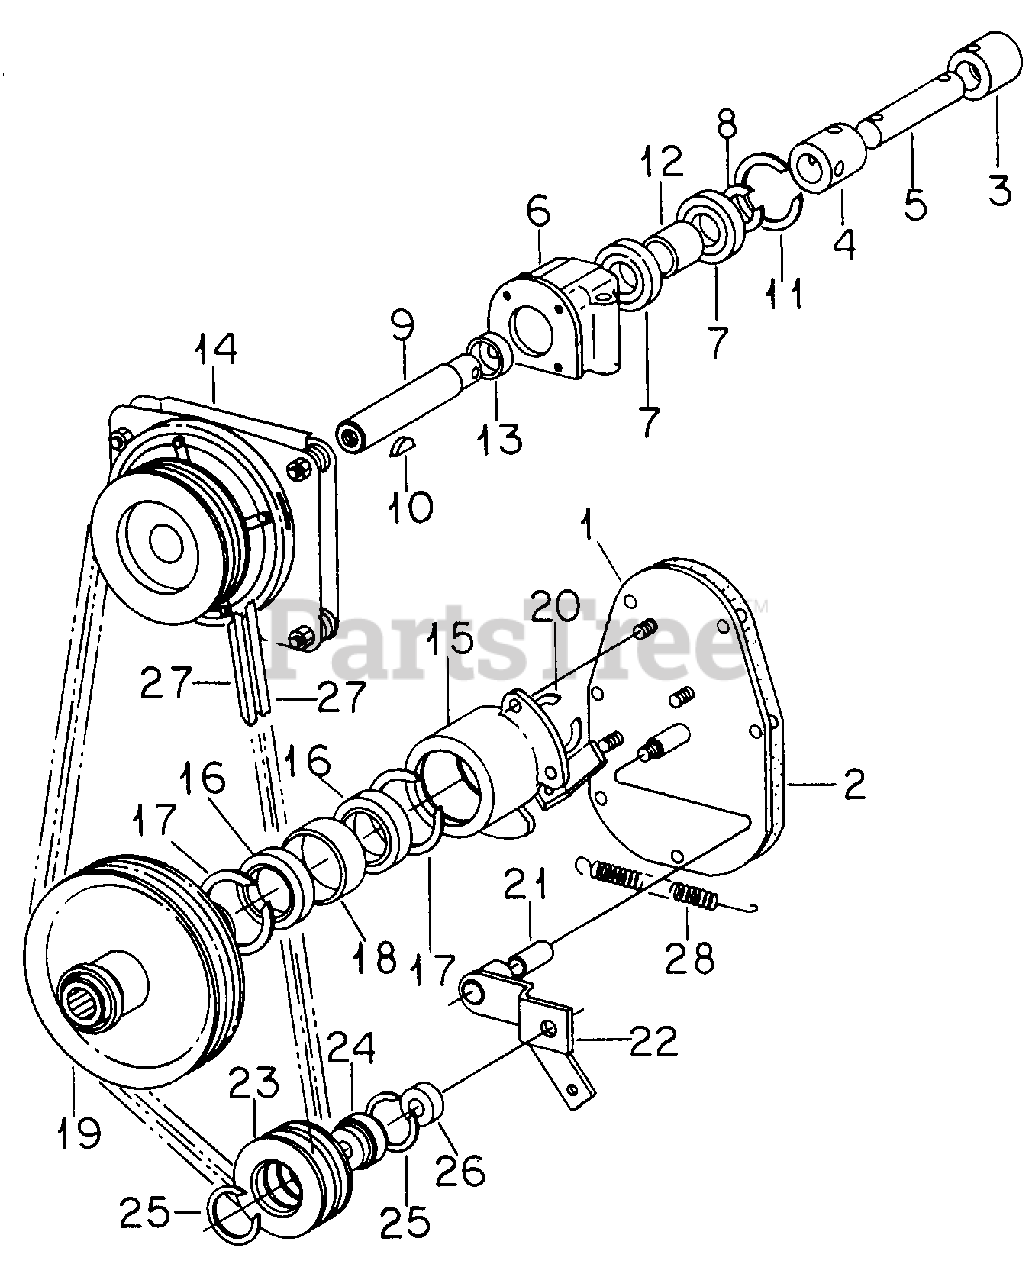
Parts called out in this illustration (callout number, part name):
1	Plate Assy, Trans Case Rear Cover
2	Gasket, Rear Cover Plate
3	Coupling, Spline
4	Coupling, Clutch Shaft to Inter-Shaft
5	Shaft, IPTO Intermediate
6	Housing, Rear IPTO Clutch Bearing
7	Bearing, Ball
8	Ring, External Snap
9	Shaft, Rear IPTO Clutch
10	Key, Woodruff #15
11	Ring, Internal Snap
12	Spacer, Inter-Shaft
13	Spacer, Rear IPTO Shaft
14	Clutch Assy, IPTO w/Pulley
15	Housing, Rear IPTO Bearing
16	Bearing, Ball
17	Ring, Snap Internal Retaining
18	Spacer, Rear Pulley Housing
19	Hub Assy, Double Pulley
20	Ring, Snap External Retaining
21	Bushing, Idler Pulley
22	Bracket Assy, Idler Pulley
23	Pulley, Idler
25	Ring, Snap Internal Retainer
26	Spacer, Extra Heavy Black Pipe
27	Belt Set, Matched
28	Spring, Rear IPTO
